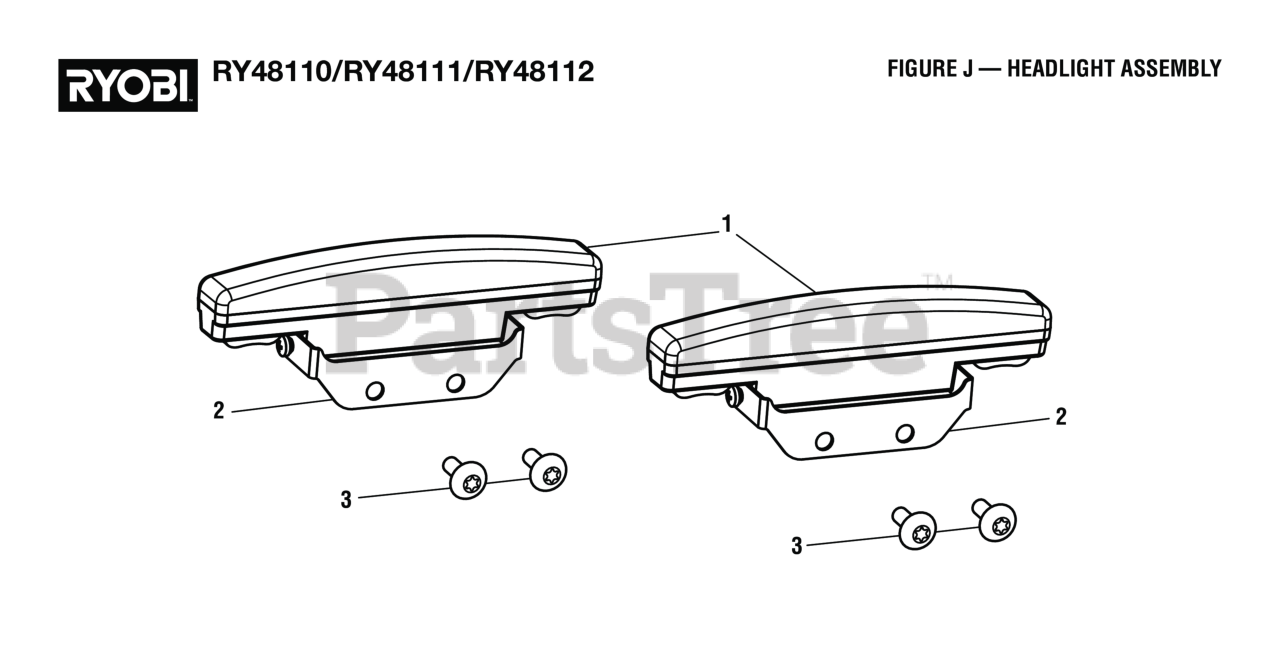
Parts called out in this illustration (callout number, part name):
1	Light Assembly
2	Bracket (Bracket Only)
3	Screw (M6 x 10 mm, Soc. Button Hd.)
